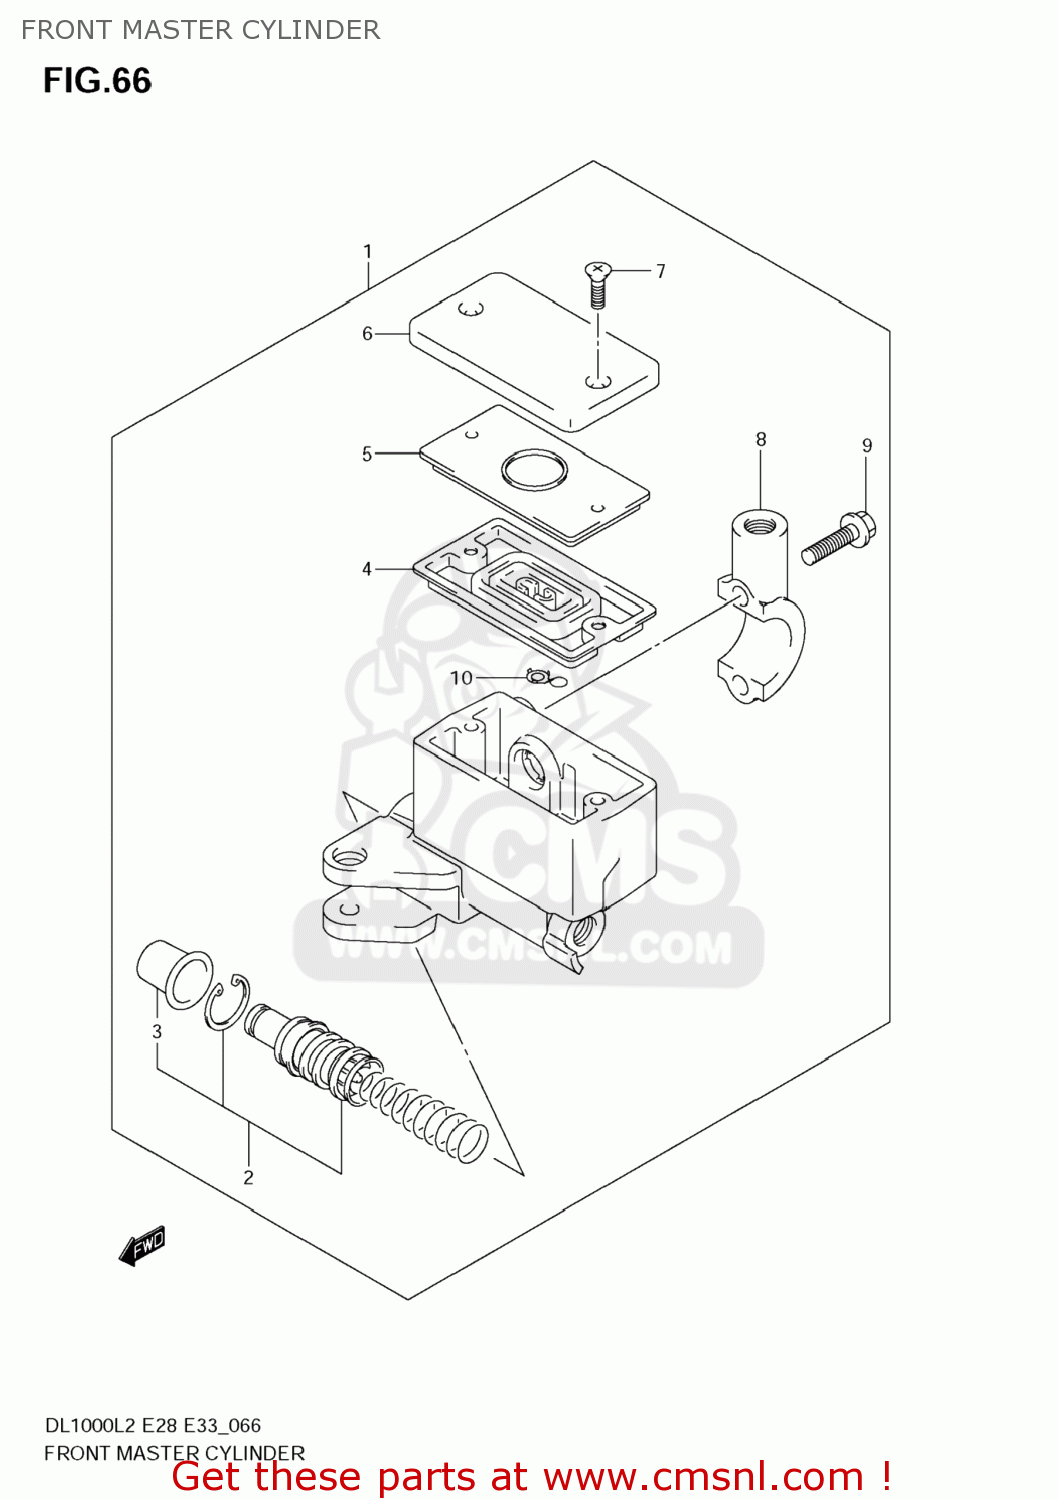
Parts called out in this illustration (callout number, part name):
1	CYLINDER ASSY,FR MASTER
2	PISTON & CUP SET
3	BOOT
4	5
5	PLATE,DIAPHRAGM
6	CAP
7	SCREW
8	HOLDER
9	BOLT(6X22)
10	PROTECTOR
